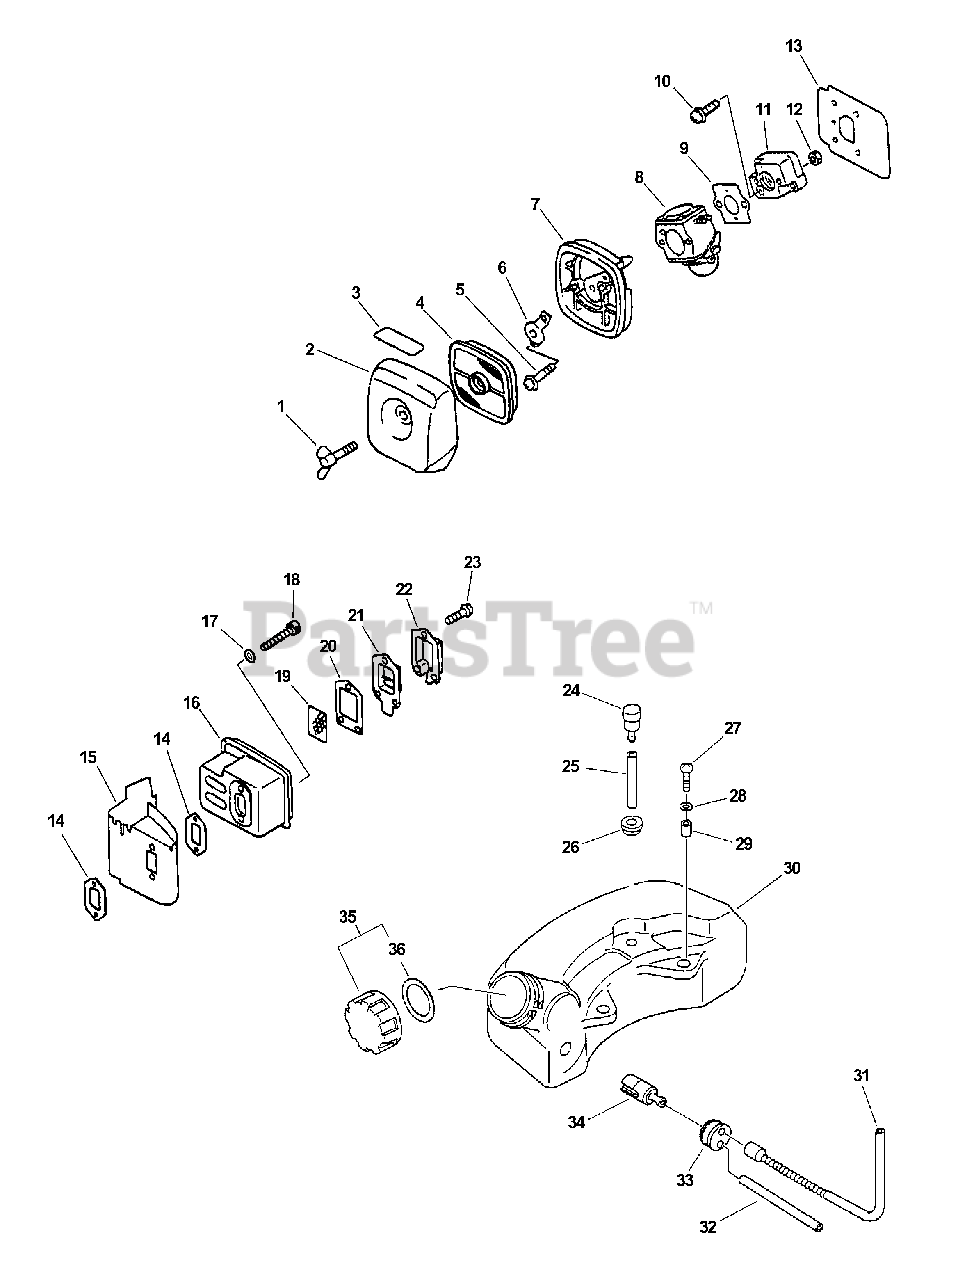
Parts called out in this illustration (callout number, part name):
1	THUMBSCREW
2	COVER, AIR FILTER - GRAY
3	LABEL - CHOKE
4	FILTER, AIR - SINGLE LAYER
5	SCREW - 5X65
6	PLATE, PREVENT
7	AIR FILTER CASE ASSY
8	CARBURETOR C1U-K51
9	GASKET, INTAKE
10	SCREW - 5X20
11	INSULATOR, INTAKE
13	SHIELD, INTAKE
14	GASKET, EXHAUST
15	COVER, EXHAUST
17	WASHER - 5
18	SCREW - 5X55
19	SCREEN, SPARK ARRESTOR
20	GASKET, EXHAUST
21	GASKET, EXHAUST - INNER
22	GUIDE, EXHAUST - OUTER
23	SCREW - 4X10
24	VENT, FUEL TANK
25	PIPE - 3X6X35 -- BLACK
26	GROMMET
27	SCREW - 5X16
28	WASHER - 5
30	TANK, FUEL
31	PIPE, FUEL - CORRUGATED
32	PIPE - 3X6X110 -- CLEAR
33	GROMMET
34	FILTER, FUEL
35	CAP ASSY
36	GASKET, CAP
